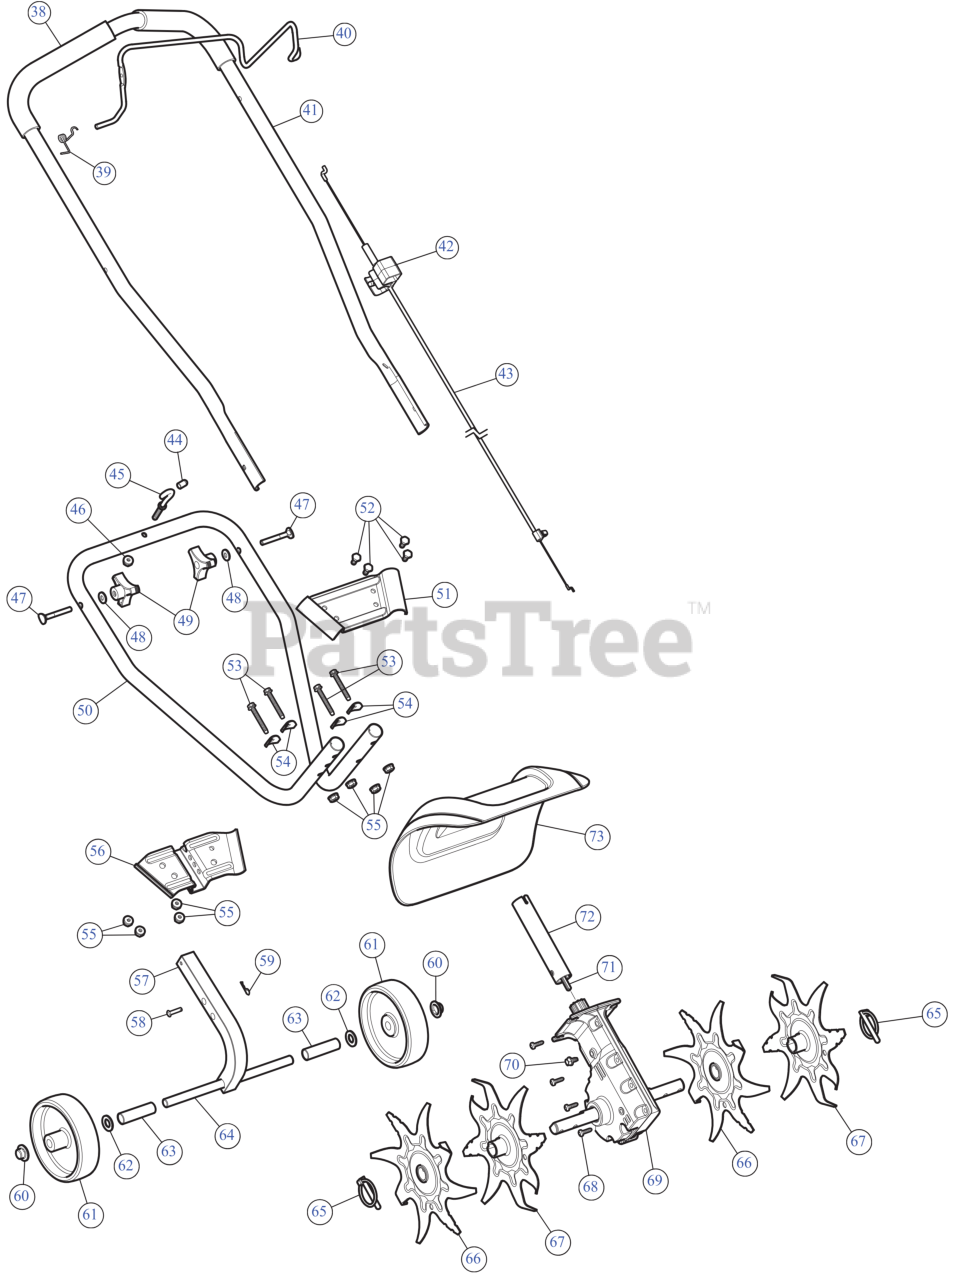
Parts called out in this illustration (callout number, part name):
38	FOAM GRIP - 9"
39	TORSION SPRING
40	BAIL CONTROL
41	HANDLE UPR
42	SW, MOMENTARY ON/O
43	THROTTLE CABLE
45	ROPE GUIDE
46	FLANGE LOCK NUT
47	BOLT, CARRIAGE CRV
48	SADDLE WASHER
49	KNOB, 3-PRONG ¼ "-
50	HANDLE LOWER
51	BRACKET UPR
52	SCREW 1/4-20X.5 GR5
53	SCREW 1/4-20 x 1.750
54	SADDLE WASHER
55	LOCK NUT 1/4
56	BRACKET LOWER
57	TUBE SQUARE
58	CLEVIS PIN
59	COTTER PIN .072 DIA. 1.13 LG
60	PUSH CAP
61	WHEEL:5.0 x 1.38
63	SPACER
65	CLICK PIN
66	TINE ASSEMBLY (LH)I (RH)O
67	TINE ASSEMBLY (LH)O (RH)I
68	SCREW #
69	GEARBOX ASSEMBLY CULT
70	SCREW 1/4-20 X.500
71	SHAFT-FLEX
72	BOOM ASSEMBLY
73	TINE SHIELD
